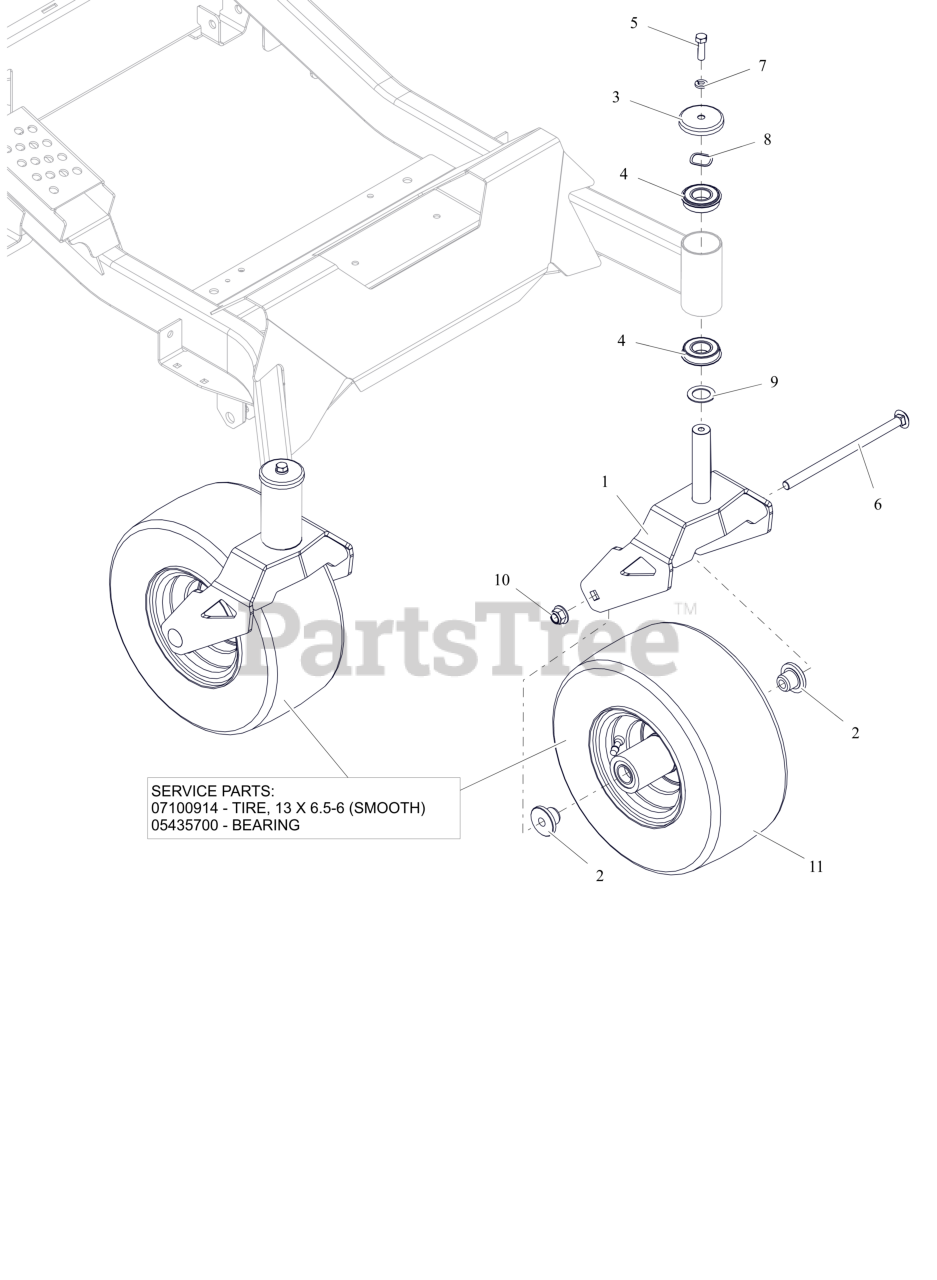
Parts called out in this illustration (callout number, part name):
1	WLDMT, CASTER FORK-HD (ORANGE)
2	SPACER, FRONT WHEEL
3	SHIELD, AXLE BEARING
4	BEARING, BALL -2.000 OD X 1.000 ID X .5625 W/RING
5	BLT, HEX .38-16X1.25 G5 ZCC
6	BLT, RHSN .50-13X9.00 G5 ZCC
7	WSHR, LK-HVY .375X.115 ZCC
8	WSHR-WAVE 1.0X1.25X.028 .145FH
9	WSHR-HRD-THRS 1.007X1.542X.062
10	NUT,NYL-FLG .50-13 GF ZCC
11	ASM, WHL/TIRE 13X6.50-6
11	LAWN TIRE FRONT, 13X6.50-6 SMOOTH
11	BRG, 25MM ID X 52MM OD X 15MM
11	TIRE TUBE, 13/6.5-6 4 PLY TR87 90 BENT VALVE
